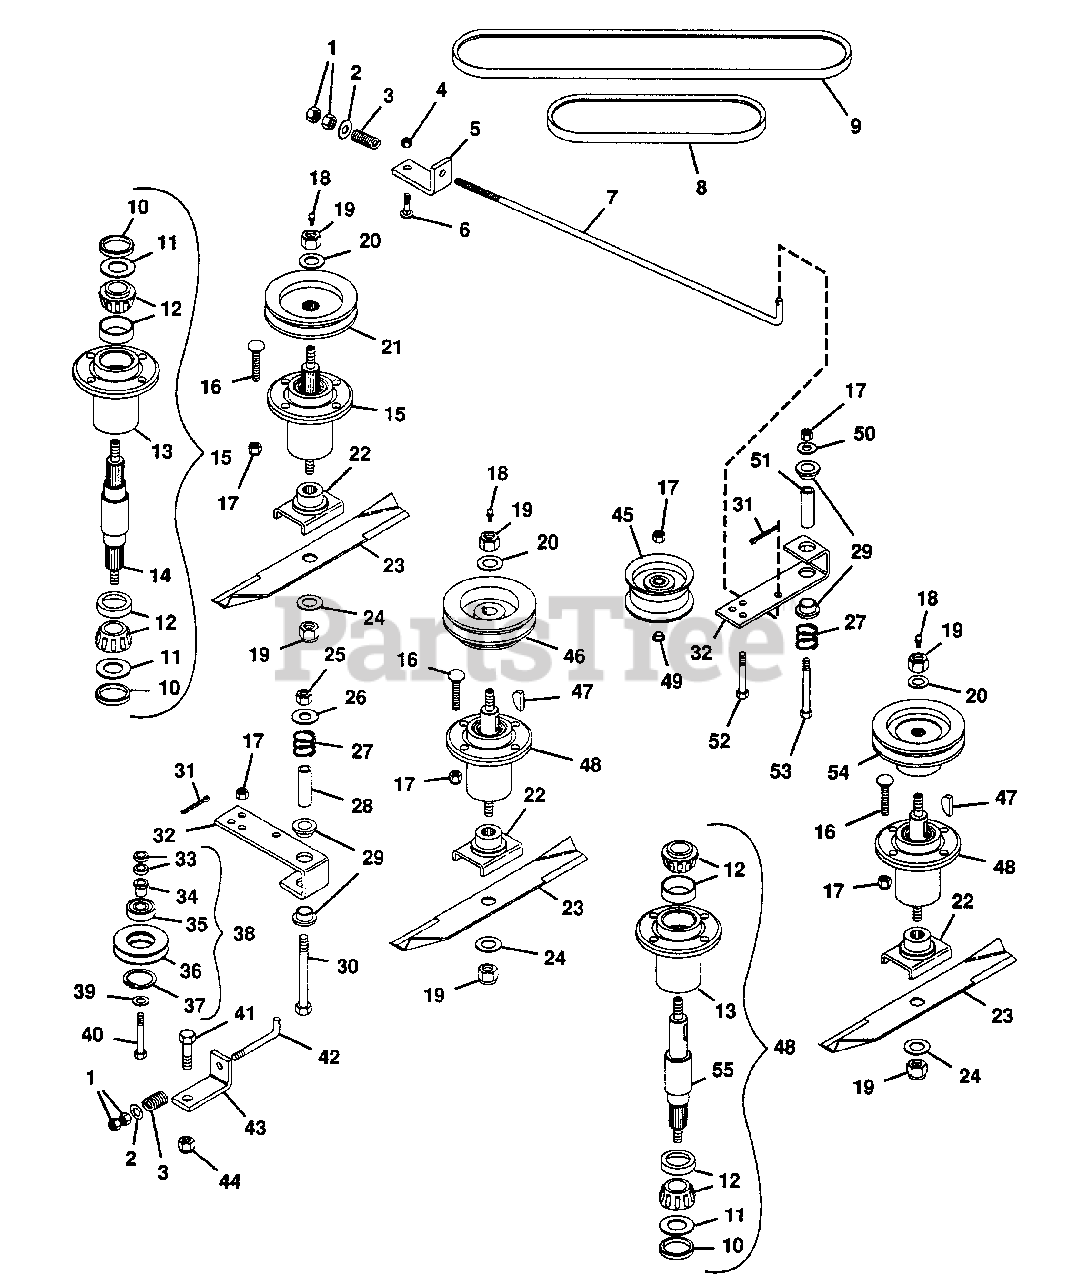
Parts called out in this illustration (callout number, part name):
1	Nut, Hex 3/8-16
2	Washer, Flat .406x.812x.065
3	Spring, Comp. 1x.78
4	Nut, Lock 5/16-18
5	Bracket, Belt Tensioner
6	Bolt, Carriage 5/16-18x1.00
7	Rod, Idler
8	Belt, Mower A44
9	V-Belt
10	Seal, Steel(Left & Center Spindles)
10	Seal, Steel(Right Spindle)
11	Washer, Flat .975x1.970x.030(Left & Center Spindles)
11	Washer, Flat .975x1.970x.030(Right Spindle)
12	Assembly, Bearing
13	Housing, Bearing
14	Shaft, Spindle
15	Assembly, Spindle
16	Bolt, 3/8-16x1.37 Rd Hd Sq Nk
17	Nut, Lock 3/8-16
18	Fitting, Lube 1/8
19	Nut, Lock 5/8-11
20	Washer, Flat .687x1.312x.122
21	Sheave, Spindle
22	Weldment, Blade Cradle
23	Blade
24	Washer, Flat .656x1.312x.095
25	Nut, Lock 1/2-13
26	Washer, Flat .531x1.250x.100
27	Spring, Comp. 1x.80x36 Lb/N
28	Bush., St. .560x.750x2.44 Stl.
29	Bush., Flg. .764x1.47x.560 Ny.
30	Bolt, Hex 1/2-13x3.50
31	Pin, Cotter .09x.75
32	Arm, Idler Pivot
33	Bush., St. .406x.750x.188 Stl.
34	Bush., Flg. .391x1.000x.760 Stl.
35	Bearing, Ball
36	Sheave, Idler
37	Ring, Retaining
38	Assembly, Idler Sheave
39	Washer, Flat .375x1.125x.065
40	Bolt, Hex 3/8-16x2.00
41	Bolt, Hex 1/2-13x1.25
42	Rod, Idler
43	Bracket, Belt Tensioner
44	Nut, Lock 1/2-13
45	Pulley, Idler
46	Sheave
47	Key, Woodruff .250x1 Hard
48	Assembly, Spindle
49	Bush., Flg. .406x.880x.270 Brz.
50	Washer, Flat .438x1.000x.083
51	Bush., St. .437x.750x2.44 Stl.
52	Bolt, Hex 3/8-16x2.25
53	Bolt, Hex 3/8-16x3.25
54	Sheave, Spindle
55	Shaft, Spindle
